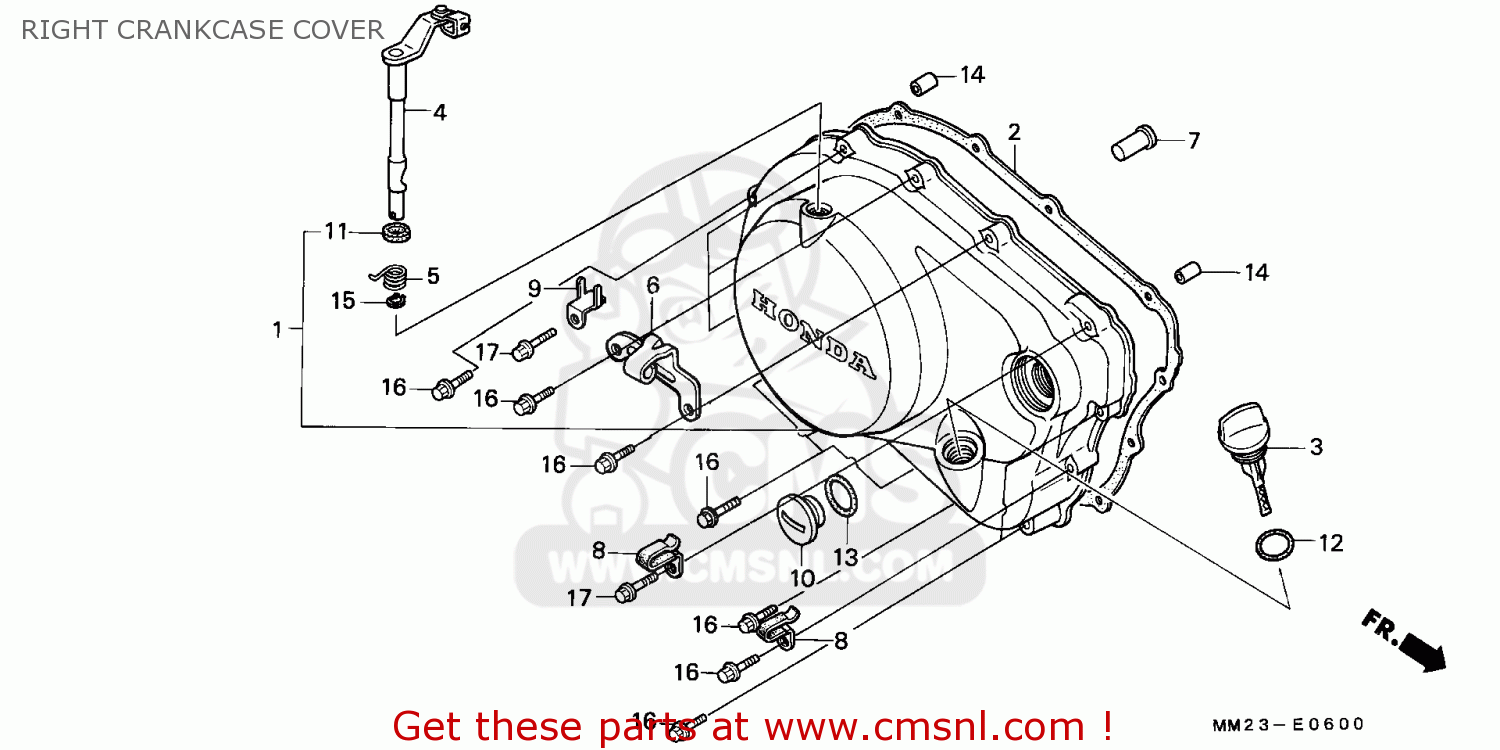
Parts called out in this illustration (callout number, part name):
1	COVER COMP.,R CRA
2	GSKT.R COVER (MCA)
3	GAUGE,OIL LEVEL
4	LEVER COMP.,CLUTC
5	SPRING,CLCH.LEVER
6	RECEIVER,CLUTCU C
7	ROD,CLUTCH LIFTER
8	CLAMP
9	CLAMP CORD
10	BOLT, SPECIAL
11	OIL SEAL 12X18X5
12	O RING,21.5M/M
13	O RING,26MM
15	CIRCLIP, 10M/M
16	BOLT,FLANGE,6X28
17	BOLT,FLANGE,6X35
